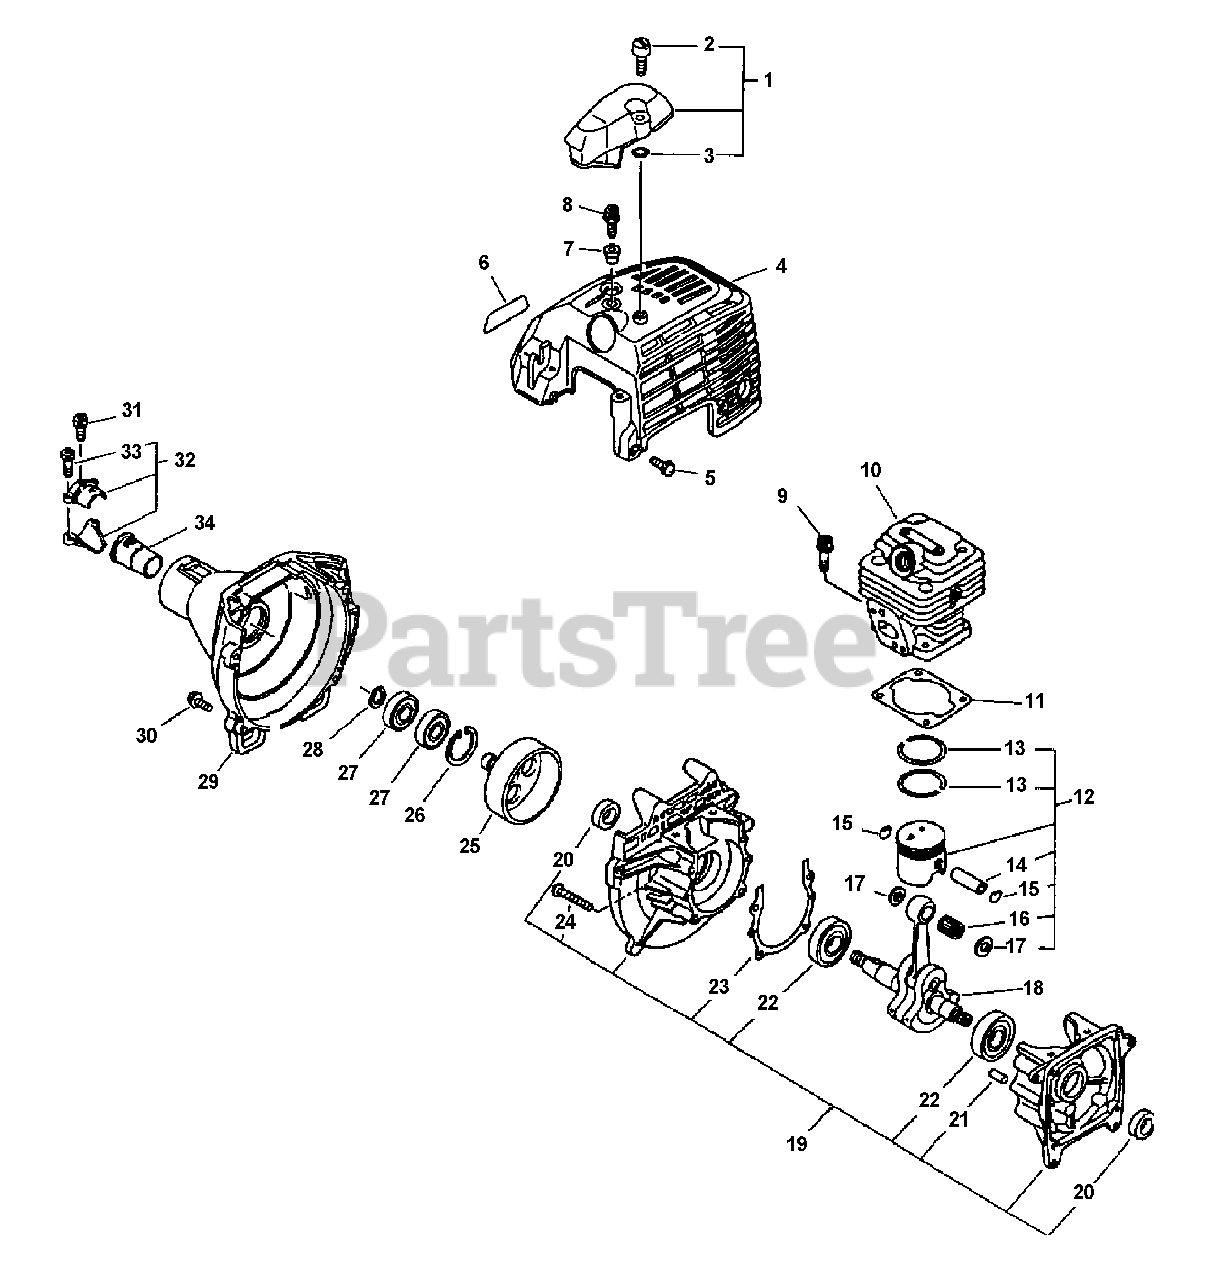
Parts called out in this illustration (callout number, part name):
1	GUARD KIT, TOP
2	THUMBSCREW M5×15.5
4	COVER, ENGINE
5	BOLT 5×12
6	LABEL, PE-3100
8	BOLT 5×20
9	BOLT 5×20
10	CYLINDER
11	GASKET, CYLINDER
12	PISTON KIT
13	RING, PISTON
14	PIN, PISTON
15	RING, RETAINING
16	BEARING, NEEDLE 9
17	WASHER, THRUST
18	CRANKSHAFT ASSY
19	CRANKCASE KIT
20	SEAL, OIL 12
21	PIN, LOCATING 4
22	BEARING, BALL - 6201 C3
23	GASKET, CRANKCASE
24	BOLT 5×30
25	DRUM, CLUTCH
26	RING, SNAP 28
27	BEARING, BALL 6001
28	RING, RETAINING - 12
29	COVER, FAN
30	BOLT 5×20
31	BOLT 5×12
32	RETAINER KIT
33	BOLT 5×25
